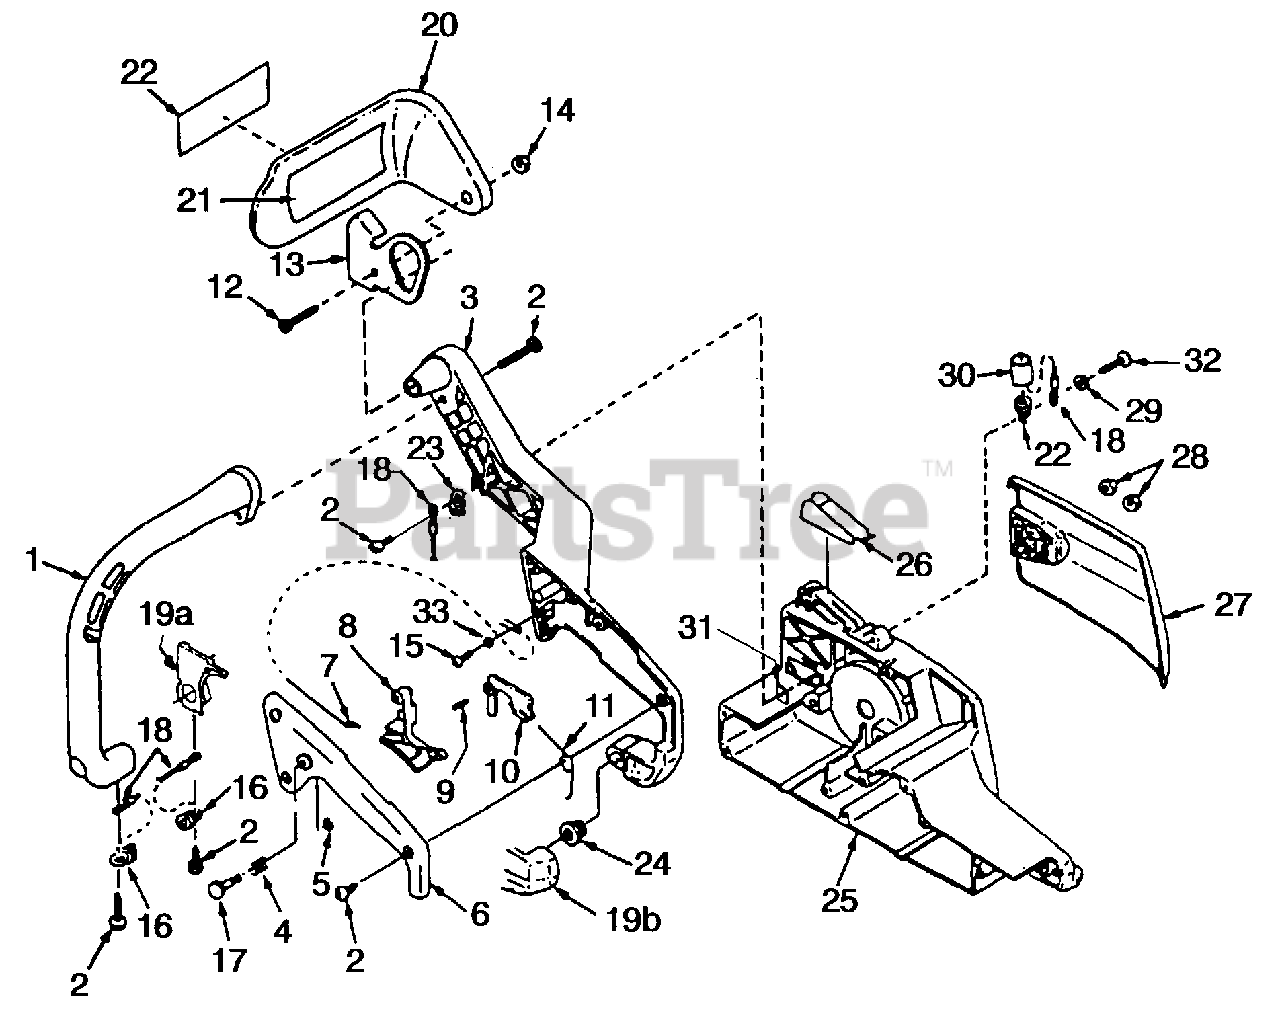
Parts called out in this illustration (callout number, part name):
1	HANDLE BAR
2	SCREW, Thread Form (8-16 X 5/8")
3	HANDLE-Rear
4	SPRING-Compression
5	RING, Retaining
6	COVER-Rear Handle
7	CABLE-Throttle
8	TRIGGER & SWIVEL
9	PIN-Dowel
10	LOCK-Trigger
11	SPRING-Trottle
12	SCREW-Hex Cap
13	MOUNTING BRACKET Handguard
14	NUT Flange Hex
15	SCREW, Thread Form (#6-19 X 7/8")
16	SPRING-Extension
17	PIN-Throttle Lock
18	RETAINER-Spring
19A	HOUSING-Starter Side
19B	HOUSING-Starter Side
20	HANDGUARD
21	DECAL-Kickback
22	DECAL-Kickback
23	SPRING-Extension
24	ISOLATOR-Vibration
25	ENGINE HOUSING-(Drive Side)
26	COVER-Snap On
27	DRIVE CASE COVER
28	NUT Hex (5/16"-18)
29	WASHER-Flat (#10)
30	SLEEVE-Spring
31	NUT Square (#10-24)
32	SCREW-Pan Hd. (#10-24 X 7/8")
33	WASHER-Flat
